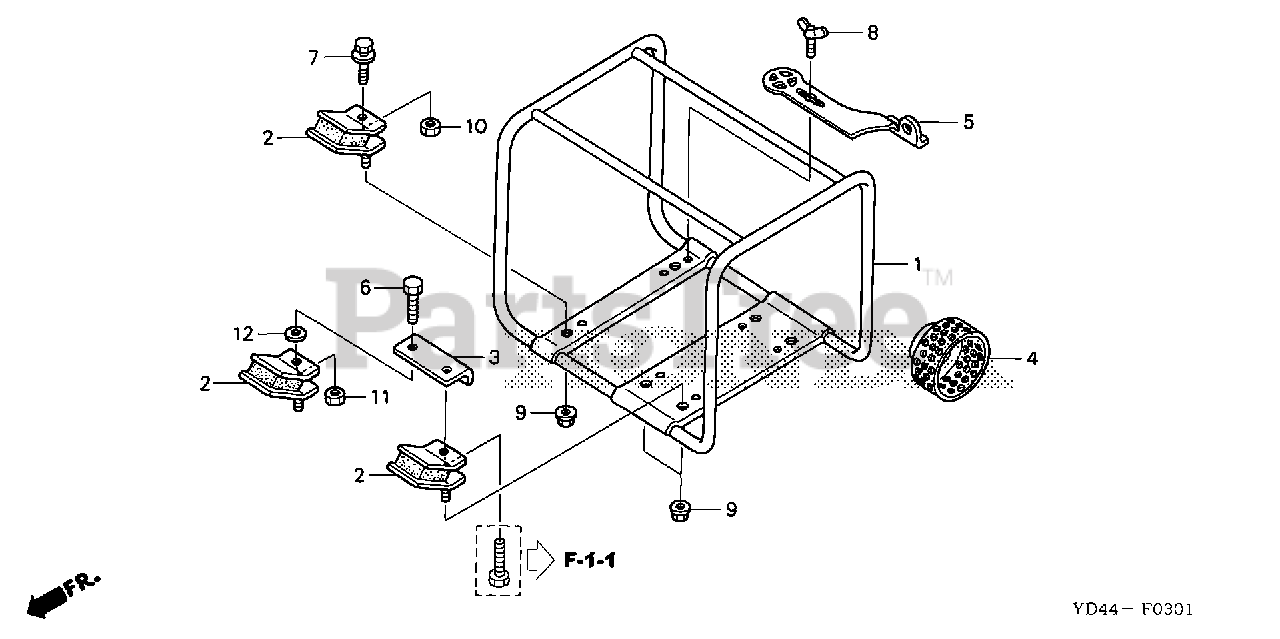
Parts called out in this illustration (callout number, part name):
2	RUBBER (LOWER)
3	PLATE, RUBBER (LOWER)
6	BOLT-WASHER (12X25)
7	BOLT-WASHER (10X40)
8	BOLT, WING (8X15)
9	NUT-WASHER (8MM)
10	NUT, HEX. (10MM)
11	NUT, HEX. (12MM)
12	WASHER, PLAIN
